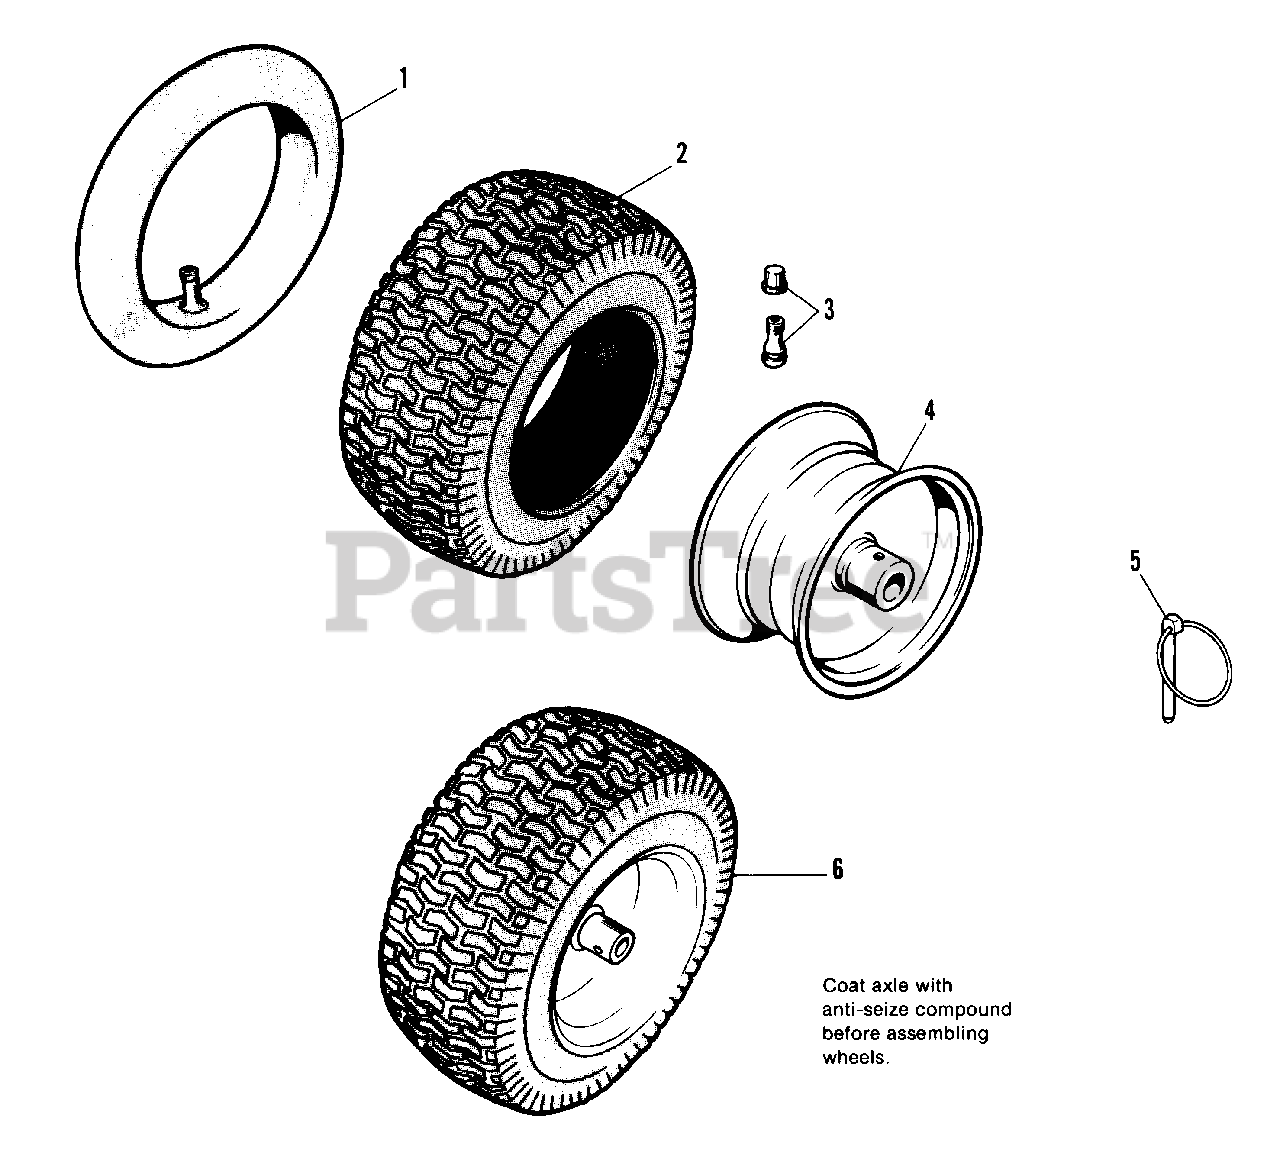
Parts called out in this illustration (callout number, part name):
1	TUBE (Service Only) 4.80/4.00-8
2	TIRE, (4.80/4.00-8)
3	VALVE STEM & CAP
4	WHEEL & HUB ASSY.
6	WHEEL & TIRE ASSY.
